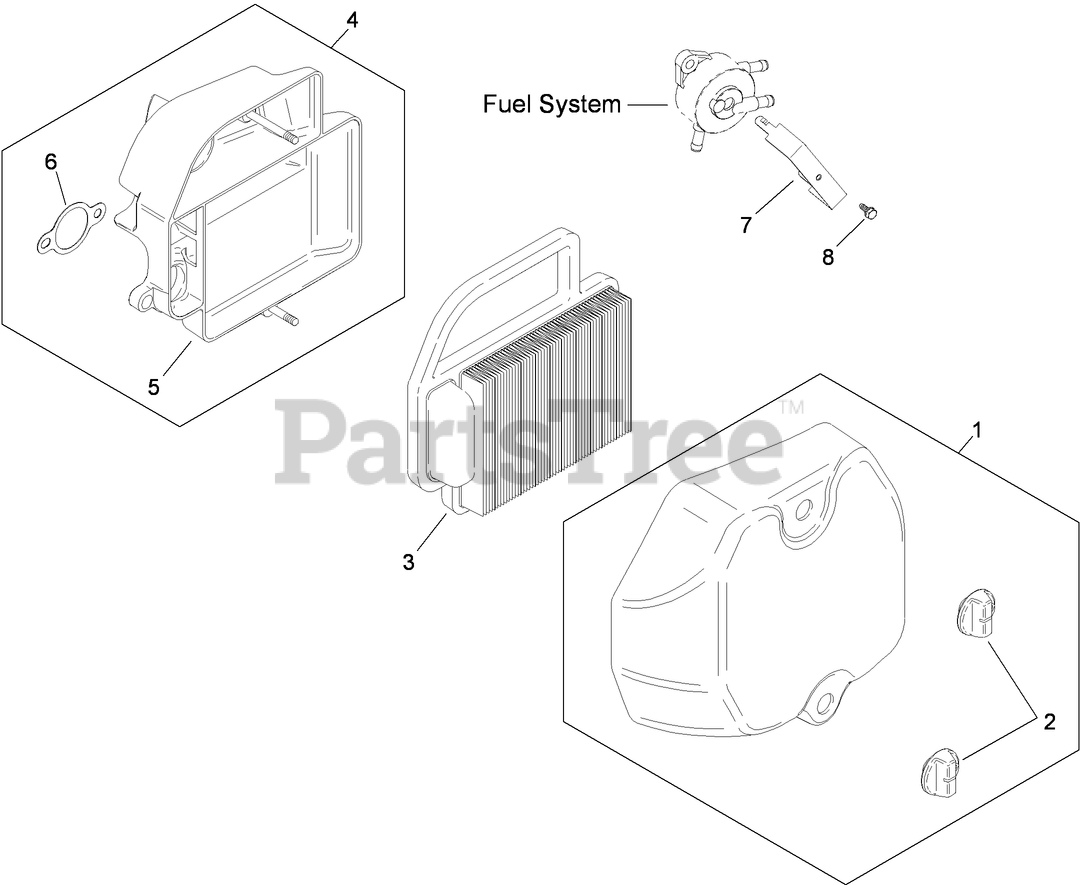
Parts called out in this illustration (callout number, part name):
1	AIR CLEANER COVER ASM
2	KNOB-COVER
3	Element-Cleaner, Air
4	AIR CLEANER BASE ASM (INCLUDES REF 1, 2)
5	STUD-BASE, AIR CLEANER
6	Gasket-Base, Air Cleaner
7	BRACKET-PUMP, FUEL
8	SCREW-THRD FRM (M4X0.7X10)
